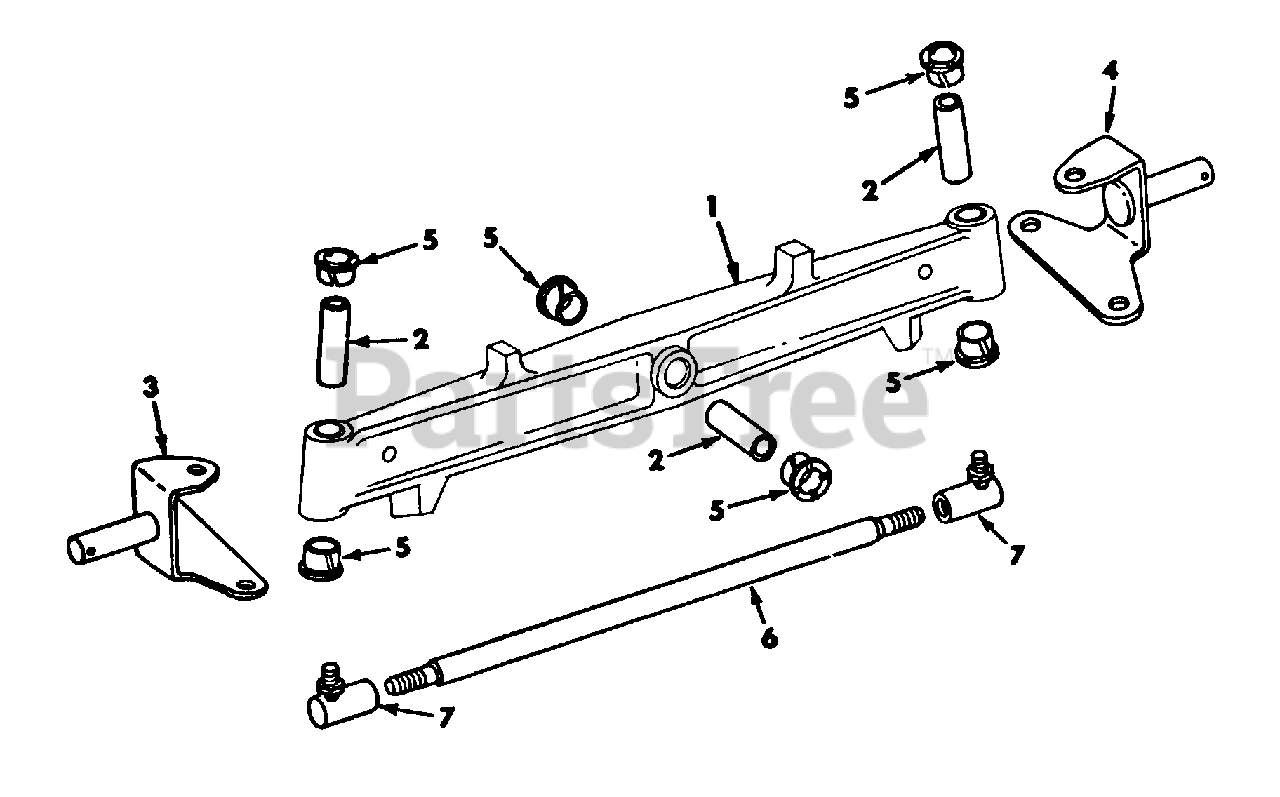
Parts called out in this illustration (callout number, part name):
2	BUSHING, FRONT AXLE
3	ARM ASSY, SPINDLE RH
4	ARM ASSY, SPINDLE LH
5	BEARING, FRONT AXLE
7	JOINT, TIE ROD
